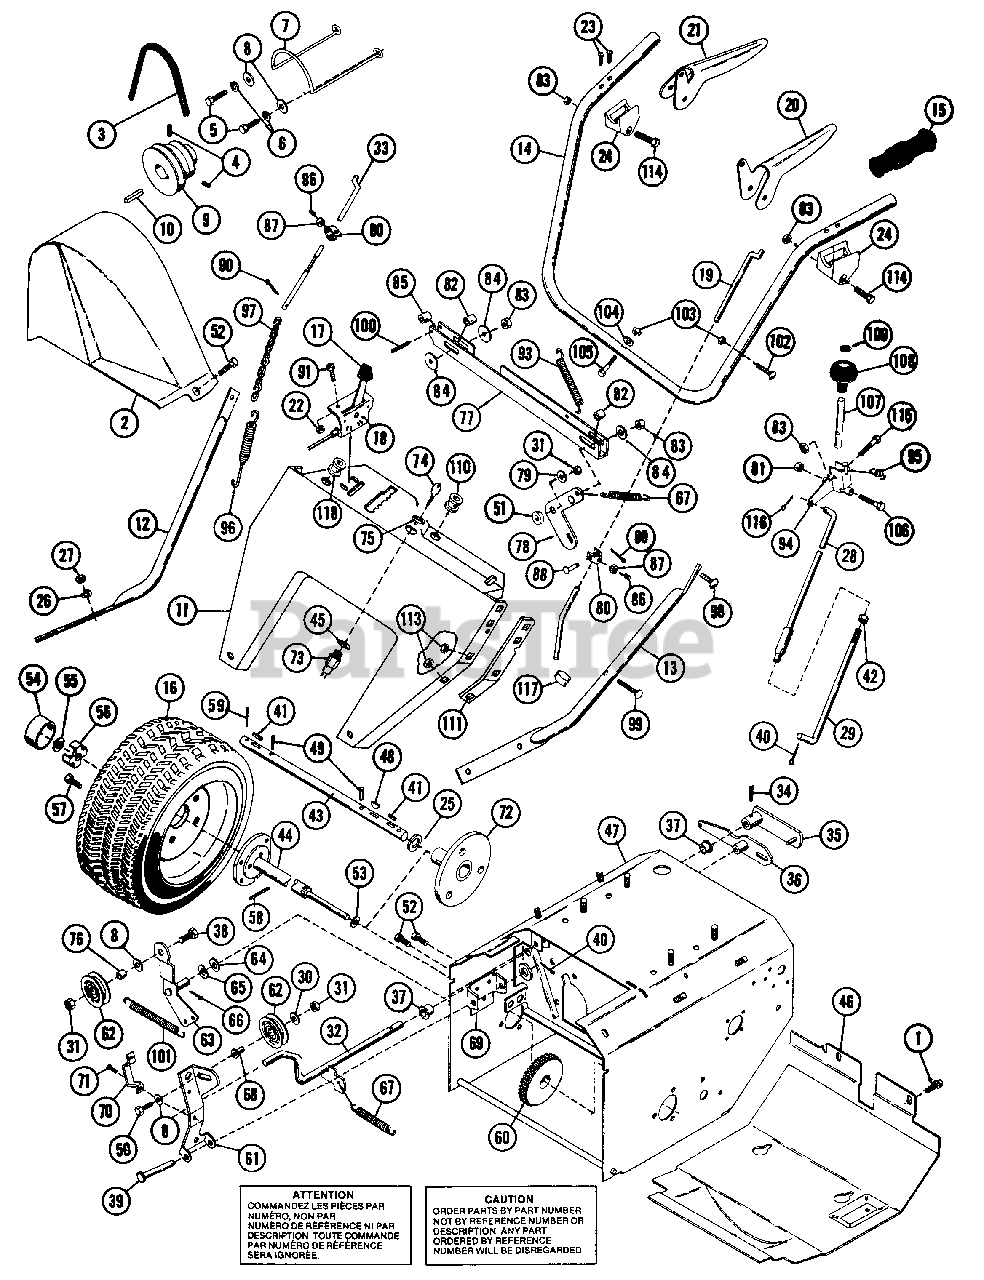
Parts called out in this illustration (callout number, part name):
1	BLT-SERHFWH .31-18X.50 PL
2	BELT COVER
3	BELT,3L 33.00 RAW LAM C-L2089
4	SCR-SET .32-18X.38 SKHCUPNL OH
5	BLT-HEX .31-24X.75 PL GR5
6	WSHR-LK-EXT .313X.030 PL
7	BELT FINGER
8	WSHR-FL-STL .38X.875X.083 PL
9	ENGINE SHEAVE
10	KEY-STR .25X1.75X.25
11	HANDLEBAR PANEL
12	LOWER HANDLEBAR RH
13	LOWER HANDLEBAR LH
14	UPPER HANDLEBAR SW
15	GRIP
16	TIRE & WHEEL ASSEMBLY CARLISLE
16	TIRE 4.10/3.50X6
16	TUBE
16	WHL 6 IN O.D.
18	THROTTLE CONTROL
19	CLUTCH ROD
20	TRACTION CLUTCH HANDLE WITH DE
21	ATTACHMENT CLUTCH HANDLE
22	NUT-KEPS 10-24 PL
23	SCR-TAP 12-14X1.50 CROVH PL BT
24	HANDLE PIVOT
25	WSHR-FL-STL .755X1.375X.125
26	WSHR-LK .375X.115 HVY PL
27	NUT-HEX .375-16
28	UPPER SHIFT ROD
29	LOWER SHIFT ROD
30	WSHR-FL-STL.312X.734X.065PL
31	NUT-LK .312-18 GR A PL
32	ACTIVATING SHAFT
33	ATTACH CLUTCH ROD
34	PIN-ROLL .156X.88
35	LEVER CLUTCH
37	BSHG-FLG.500X.625X.312X.750NY
38	BLT-HEX .31-18X1.00 PL GR 2
39	PIN-CLEV .309X2.25
40	PIN-COTR .09X.75 PL
41	KEY-FTHR .188X1.25X.187 SAE
42	NUT-HEX .312-24 PL
43	AXLE SHAFT
44	NOT USED ON THIS MODEL
45	WSHR-LK-INT .625X.045 PL
46	BOTTOM COVER
47	FRAME
48	KEY-WDRF .25X.750X.313 SAE91
49	PIN-ROLL .188X1.25
50	BLT-HEX .31-18X1.25 PL GR2
51	SPACER BUSHING .5 X .32 X .163
52	BLT-SERHFWH .25-20X.50 PL
53	NOT USED ON THIS MODEL
54	HUB CAP
55	NOT USED ON THIS MODEL
56	SPINDLE CUP
57	BLT-WHL .50-20X.75 GR5 PL
58	NOT USED ON THIS MODEL
59	PIN-COTR .12 X 1.25 PL
60	SPUR GEAR, FELLOWS 35T .750 ID
61	ARM, IDLER
62	IDLER
63	IDLER ARM
64	WSHR-FL-STL .382X.812X.023 PL
65	WAVE WASHER .406X.750X.063FH
66	PIN-COTR .12X1.0 PL
67	SG-TENS .062X.43X5.75 WLD 20
68	SPCR, BRG .315X.50X.688X.281
69	BRACKET
70	RETURN CLIP
71	SCR-TAP 10-24X.375 HWH PL TR
72	WHEEL HUB
73	SWITCH & KEY SET ASSEMBLY
74	KEYS
75	NUT .625-32 ALUM
76	SPACER .50 X .32 X .42
78	BELLCRANK
79	WSHR-FL-STL .328X.875X.062 PL
81	NUT-LK .312-18 GR A PL
82	BSHG-SLV .250X.375X.640
83	NUT-LK-CTR .250-20 PL
84	WSHR-FL-STL .281X1.250X.048PL
85	BSHG-SLV .188X.500X.480
86	SCR-SET .25-20X.75 SKHCUP OH
87	NUT-HEX JAM .25-20 YWZC
88	CLEVIS PIN
89	PIN-HAIR INT .06X.18X.77
90	PIN-COTR .12X.50 PL
91	SCR-MCH 10-24X.50 SLRH BL
93	SG-TENS .035X.45X2.75 WLD 3.5
95	SG-TENS .055X.33X1.31 WLD 7
96	SG-TENS .091X.56X6.12 WLD 40
97	CLUTCH CHAIN
98	BLT-RDHDSQNK .31-18X.62 PL BL
99	BLT-RDHDSQNK .31-18X1.50 PL BL
100	PIN-ROLL .188X.88
101	SG-TENS .080X.73X3.06 WLD 20
102	BLT-RDHDSQNK .25-20X1.50 PL BL
103	NUT-LK-FLG .250-20 PL
104	WSHR-FL-STL .265X.500X.087 PL
105	BLT-HEX .25-20X1.50 GR5
106	BLT-HEX .31-18X2.50 PL GR2
107	ROD
109	RG-RTNG-EXT .500X.015
110	SNAP BUSHING
111	R H STIFFENER
111	L H STIFFENER
113	NUT-FLG. .312-18 PL
114	BLT-HEX .25-20X1.50 PL GR5
115	BLT-HEX .25-20X1.00 GR2
116	PIN-COTR .12X.75 PL
118	SNAP BUSHING-.437
